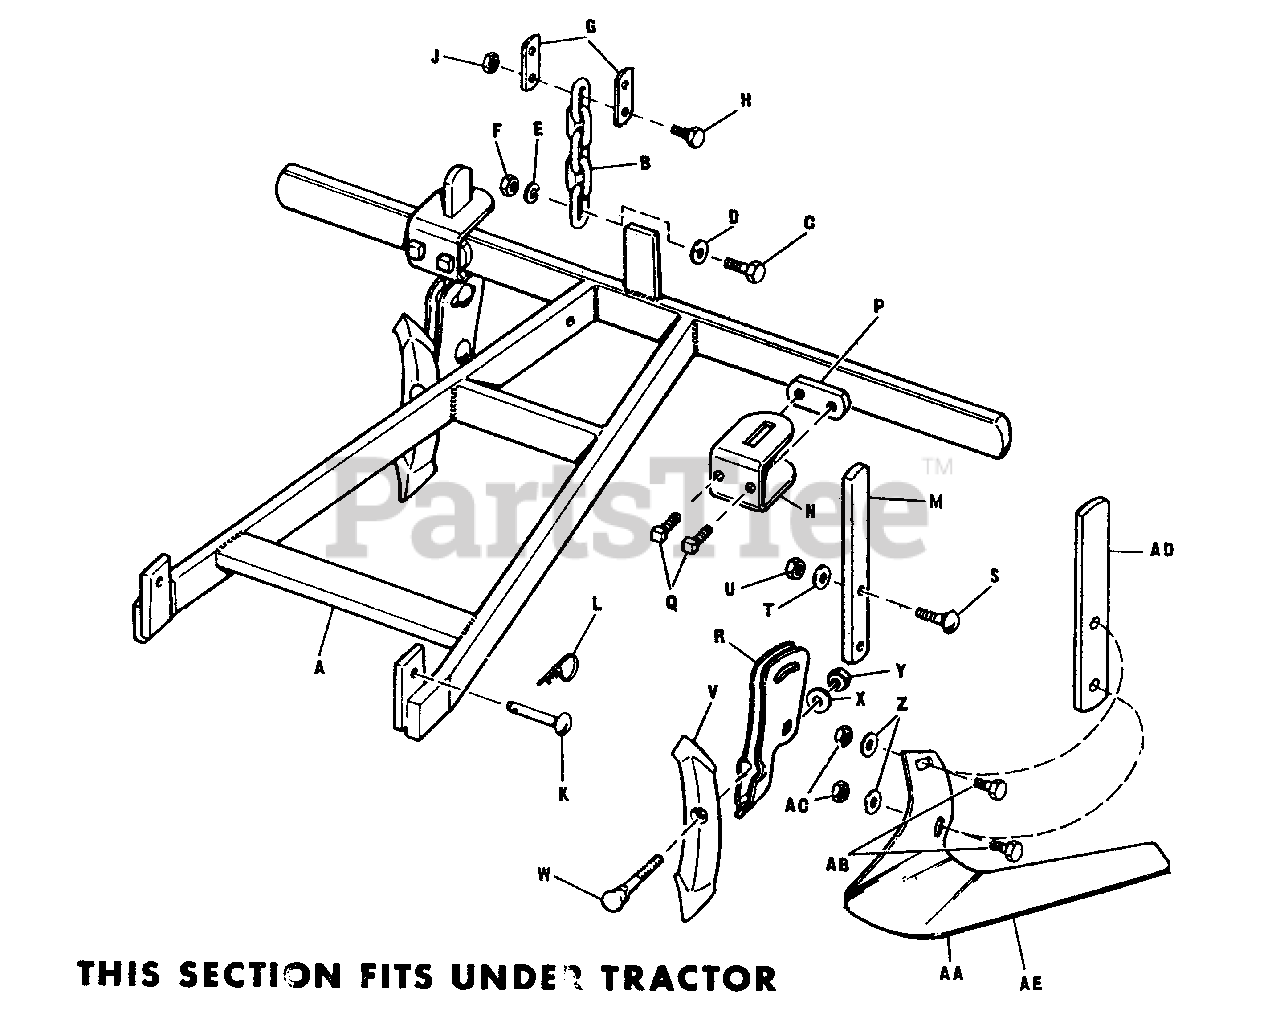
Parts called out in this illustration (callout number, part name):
A	Front Bar Tool Assembly
B	Chain
C	Hex. Hd Cap Screw, 3/8"-16 x 1-1/4
D	Plain Washer, 3/8"
E	Lock Washer, 3/8"
F	Full Hex. Nut, 3/8"-16
G	Link, 1/8" x 1 x 2-1/2"
H	Hex. Hd. Cap Screw, 3/8"-16 x 1"
J	Hex. Full Lock Nut, 3/8"-16
K	Pin
L	Spring Clip
M	Short Standard Tool, 7/16" x 1-1/4" x 8-5/8"
N	Clamp Shank, 3/16" x 2" x 8"
P	Special Nut, 5/16" x 1" x 2-1/2"
Q	Set Screw, 3/8"-16 x 1"
R	Tool Holder Assembly
S	Carriage Bolt, 3/8"-16 x 1-1/4"
T	Plain Washer, 3/8"
U	Full Hex. Nut, 3/8"-16
V	Cultivator Teeth, 1/4" x 1-1/2" x 9"
W	Plow Bolt, 3/8"-16 x 1-3/4"
X	Plain Washer, 3/8"
Y	Full Hex. Nut, 3/8"-16
Z	Plain Washer, 3/8"
AA	Hoe, R.H.
AB	Hex. Hd. Cap Screw, 3/8"-16 x 1 "
AC	Full Hex. Nut, 3/8"-16
AD	Tool Standard
AE	Hoe, L.H.
